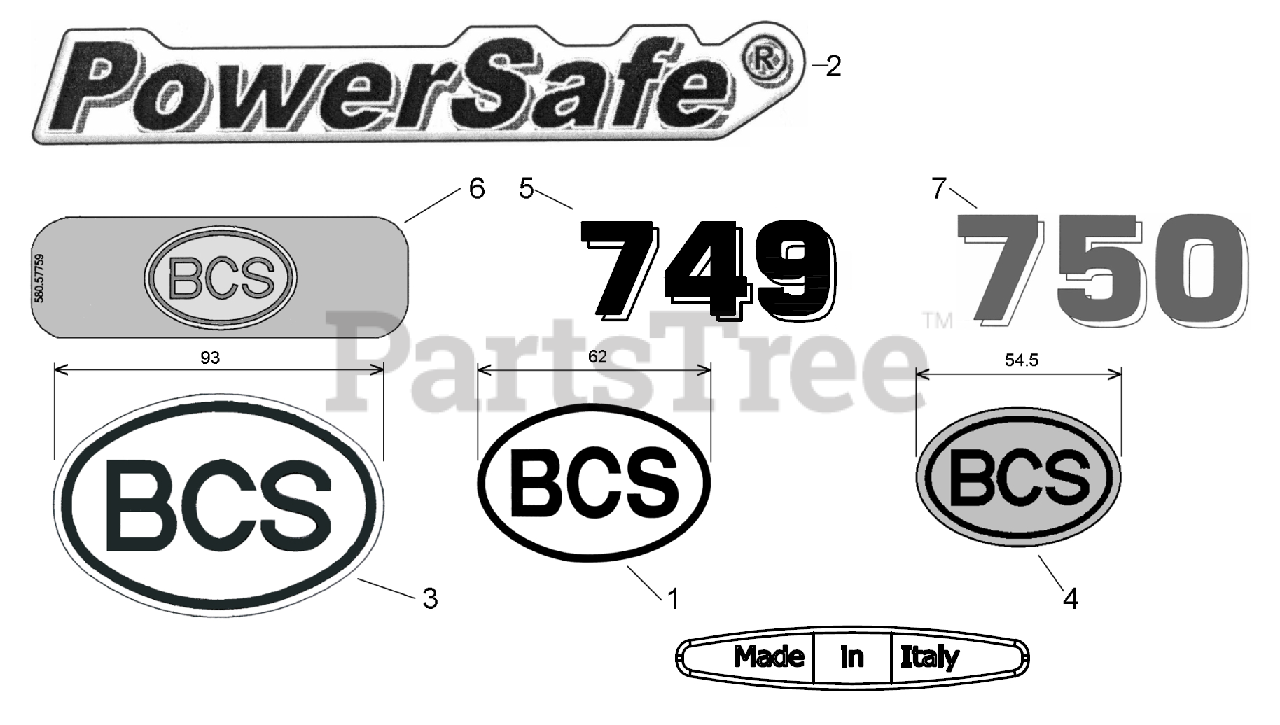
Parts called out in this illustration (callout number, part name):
1	DECAL - BCS LOGO 62MM
2	DECAL - POWERSAFE
3	DECAL - BCS LOGO 93MM
4	DECAL - BCS LOGO 54.5MM
5	DECAL - 749
6	DECAL - BCS LOGO
7	DECAL - 750
8	DECAL
